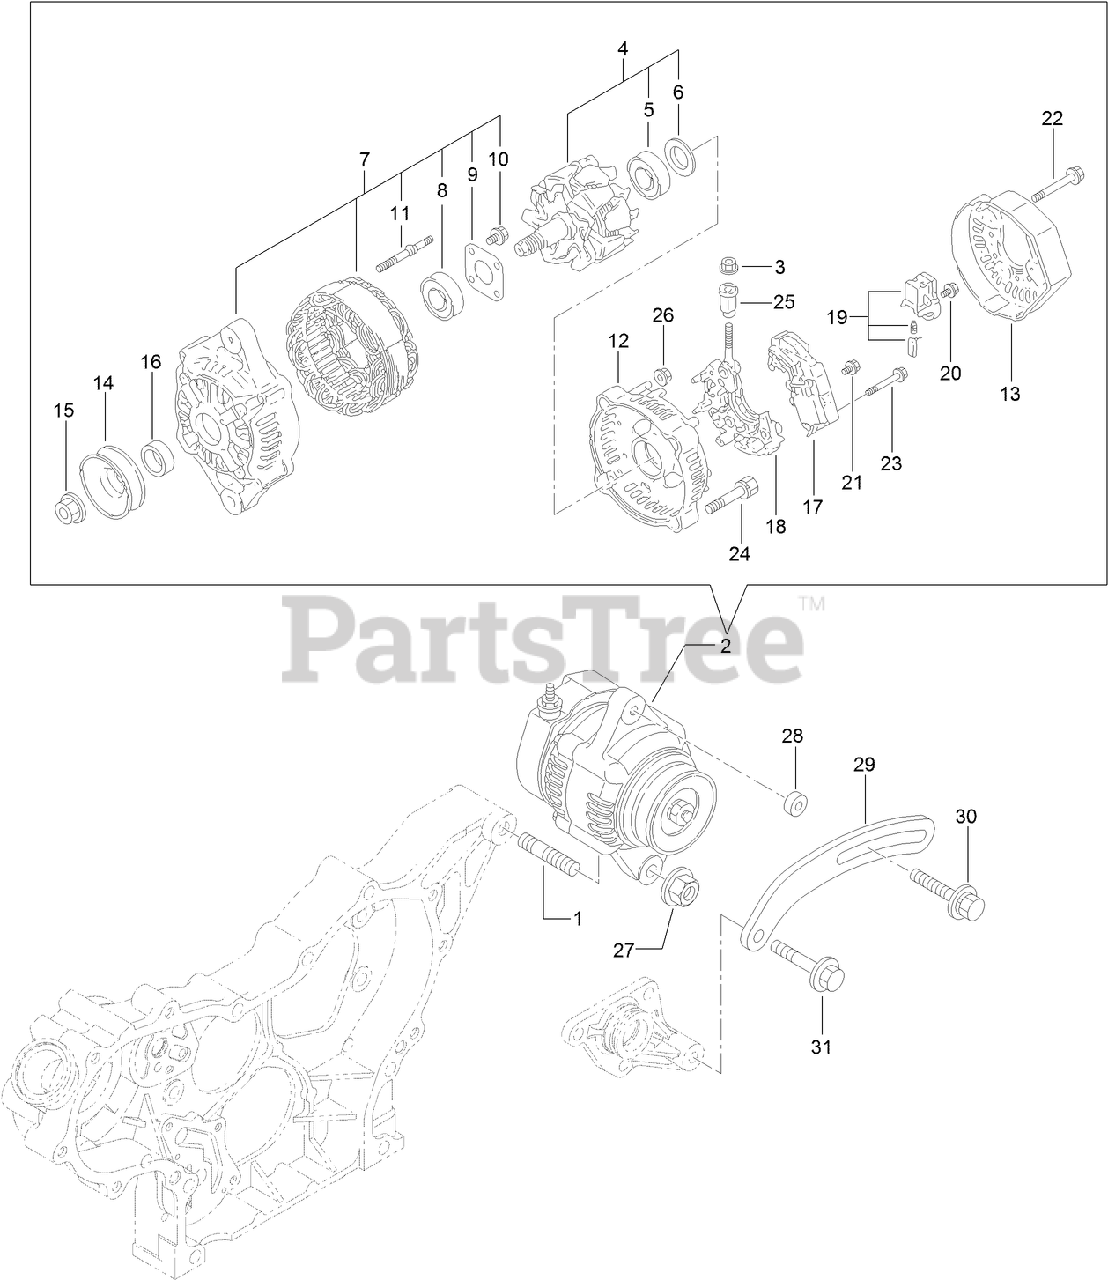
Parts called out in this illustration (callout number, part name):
2	GENERATOR
4	ROTOR ASM
5	BEARING-BALL
7	FRAME ASM
8	BEARING-BALL
9	PLATE-RETAINER
14	PULLEY
16	COLLAR
17	REGULATOR ASM
18	HOLDER
19	HOLDER
25	BUSHING-INSULATION
28	SPACER
29	ADJUSTER
